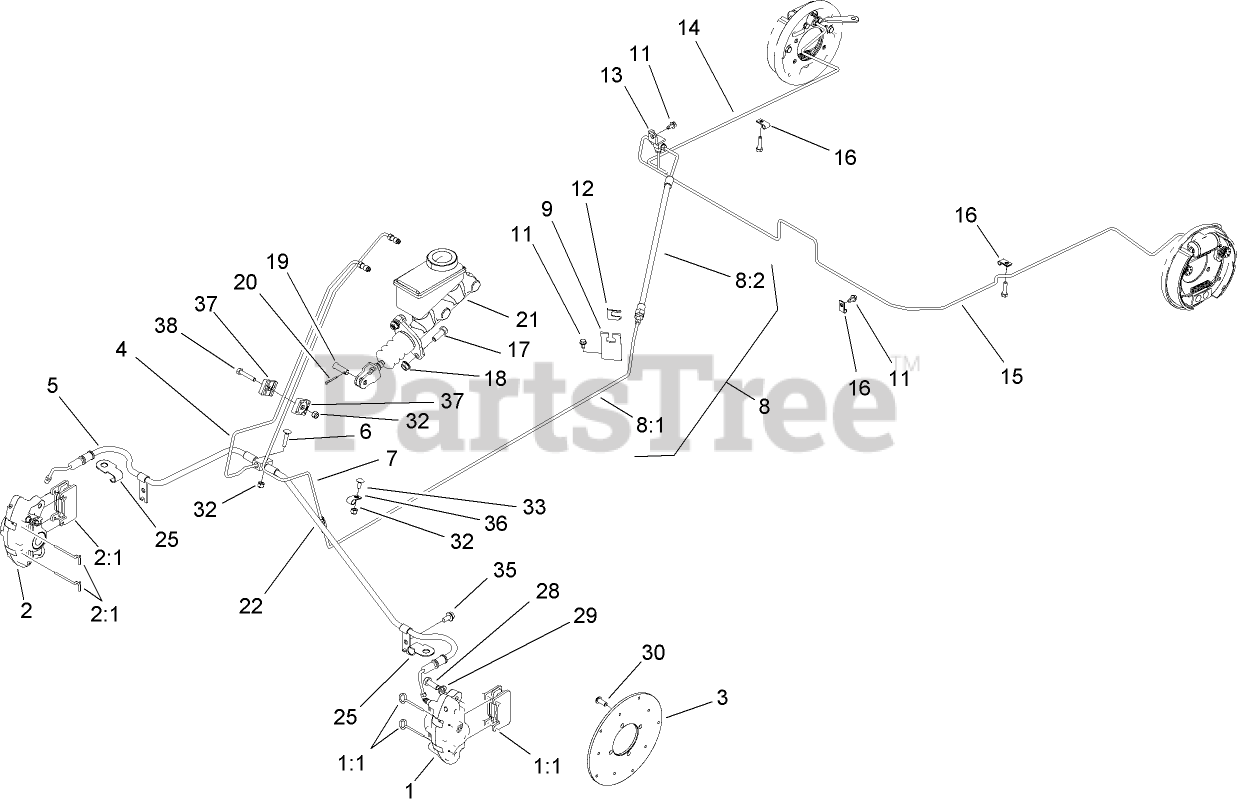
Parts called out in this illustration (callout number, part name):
1	CALIPER-LH
1:1	FRICTION PAD AND PIN KIT
2	SEE PARTS BULLETIN #977
2:1	FRICTION PAD AND PIN KIT
4	TUBE-BRAKE, FRONT
6	SCREW-CARR
7	TUBE-BRAKE, REAR
8	Loose Parts Package
8:1	TUBE-BRAKE, REAR
8:2	HOSE-BRAKE, REAR
9	BRACKET-HOSE, BRAKE
11	SCREW
14	TUBE-BRAKE, REAR (RH)
15	TUBE-BRAKE, REAR (LH)
16	CLIP-CLOSED, INSULATED
17	SCREW-HH
18	NUT-HHF, WHIZ
19	PIN-CLEVIS
20	PIN-COTTER
21	MASTER CYLINDER ASM
22	UNION
25	BRACKET-HOSE
28	SCREW-HH
29	WASHER-LOCK
30	SCREW-HSBH
32	NUT-LOCK, NI
33	SCREW-CARR
35	SCREW-HWHTF
36	CLAMP-R
37	CLAMP-TUBE
38	SCREW-HH
